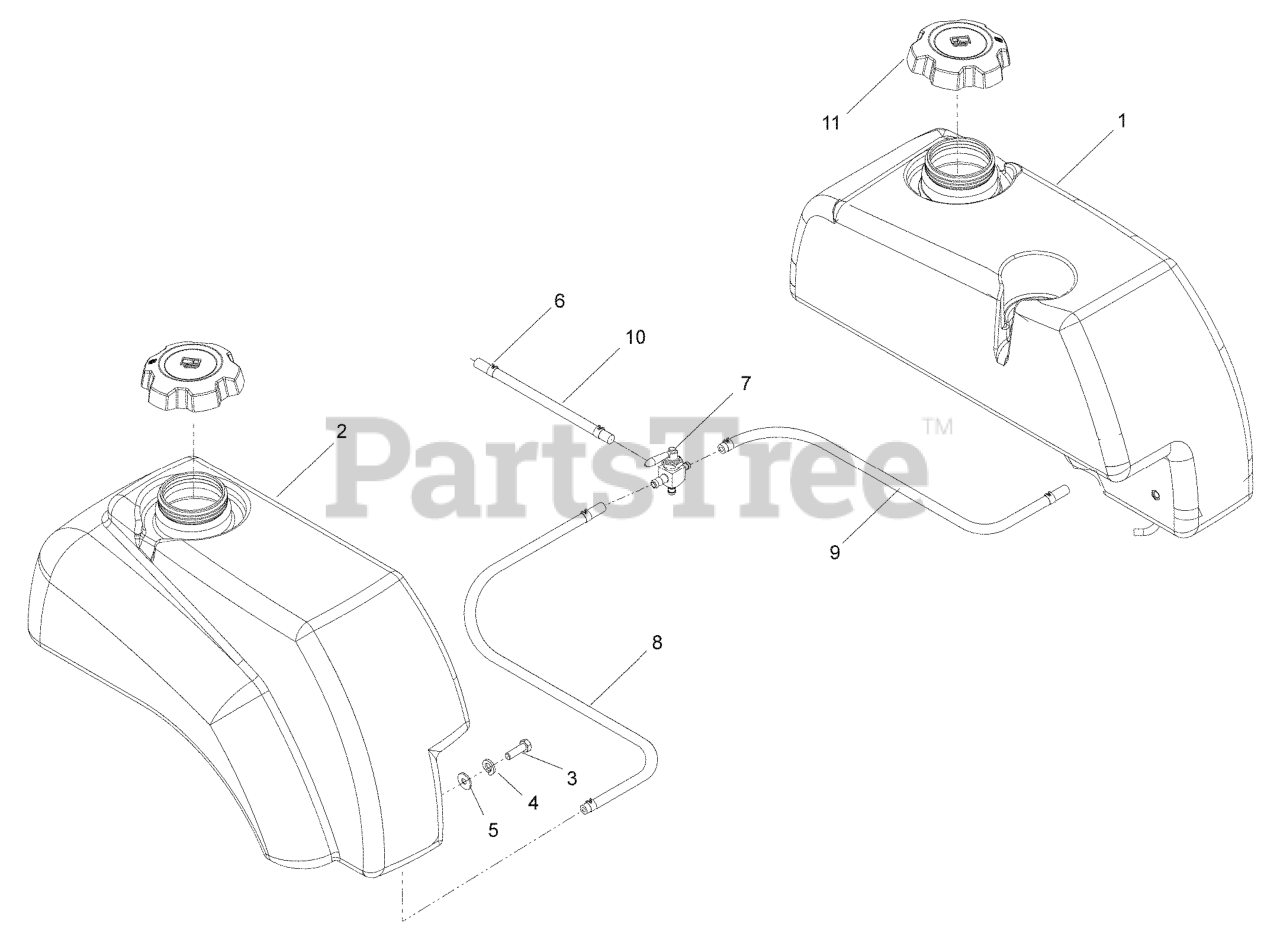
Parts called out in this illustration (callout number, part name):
1	LEFT TANK W/CUP HOLDER
2	FUEL TANK RT
3	HCS 5/16C X 3/4
4	WASHER.LOCK.HVY.HLCL.SPR.5/16
5	WASHER 5/16 FLAT
6	HOSE CLAMP
7	FUEL VALVE
8	FUEL LINE 24"
9	HOSE 1/4 X 28
10	FUEL LINE 13"
11	FUEL CAP, HTC
